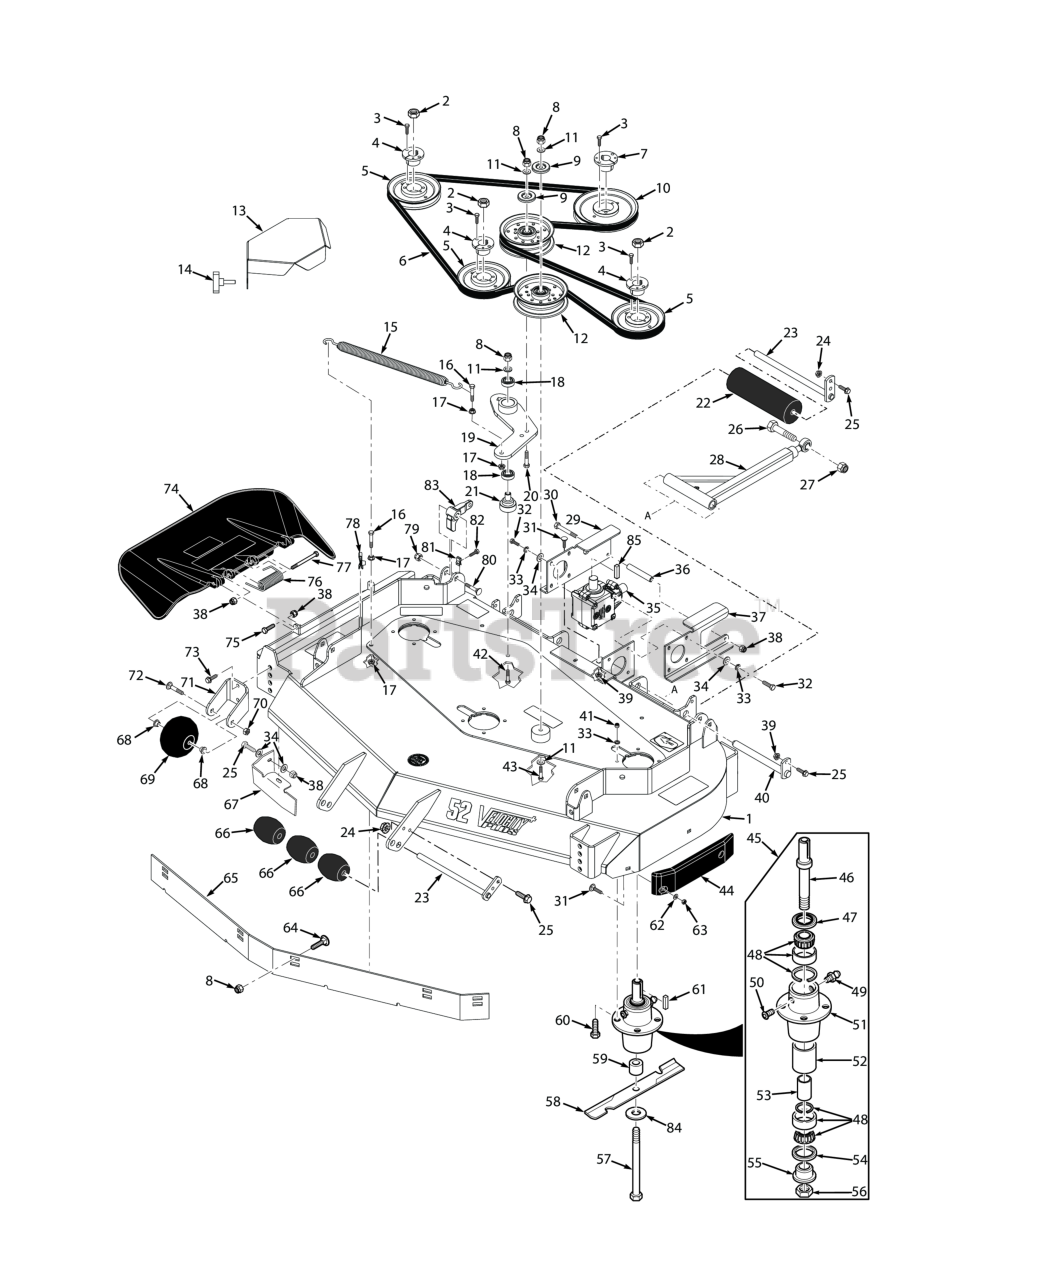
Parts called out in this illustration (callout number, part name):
1	Cutter Deck w/Decals - 52V
2	Hex Locknut, Elastic Stop, 3/8-16
3	Bolt, Hex Head 1/4-20 x 1" Grade 8 Black
4	Hub, Tapered 1-1/8" Bore
5	Pulley, 5.75 O.D. (Gasoline Engines)
6	Belt, Cutter Deck Drive
7	TAPERED HUB, 1.00" BORE
8	HEX NUT, ELASTIC STOP LOCK, 3/8-16
9	Quick Pin, 5/16" Dia.
10	Pulley, 6.95" O.D. - 72"
11	Flatwasher, 3/8 (.391 x .938 x .105 HD) Grade 8
12	Idler Pulley, Belt Clutch
13	Belt Cover LH
14	Knob, w/stud 3/8-16 x 1-1/4"
15	Spring, Cutter Deck
16	Bolt, Hex Head 3/8-16 x 1-1/2" Grade 8 Black
17	NUT, 3/8-16 SERRATED FLANGE HEX HEAD
18	BEARINGS, BALL, NEUTRAL RETURN
19	Idler Arm, Cutter Deck
20	Capscrew, Hex Head 3/8-16 x 2.75"
21	Pivot, Idler - Short
22	Wheel, Anti-ScalpRelief Fitting, Tapered Spindle
23	Shaft Weldment, Guide Roller
24	Nut, Flange Head Elastic Stop 5/16-18
25	Bolt, Heax Head 5/16-18 x 1" (48V / 52V)
26	BOLT, HEX HEAD 5/8-11 X 4-1/2"
27	HEX LOCKNUT, ELASTIC STOP, 5/8-11
28	Push Arm (Includes 64,60,62)
29	Mounting Plate
30	Bolt, 5/16-18 x 4-3/4" Hex Head
31	Bolt, 5/16-18 x .75 RHSN Carriage
32	Bolt, Heax Head 5/16-18 x 1" (48V / 52V)
33	Lockwasher, 5/16 (.317 x .586 x .078) Helical Spring
34	Flatwasher, 5/16-.375 x .875 x .083 (35BV & 37BV-EFI)
35	Gearbox Assembly, Deck Drive
36	Spacer, Gearbox Mount
37	Mounting Plate
38	HEX NUT, ELASTIC STOP LOCK, 5/16-18
39	Nut, Serrated Flange 5/16-18 (Right Front Engine Mounting, Briggs and Kohler Only)
40	Shaft Weldment, Pusharm
41	Lock Nut, 5/16-18 Elastic Stop Grade 8
42	Bolt, Hex Head 3/8-16 x 3" - 52"
43	Capscrew, Hex Head 3/8-16 x 3-3/4"
44	Pad, Deck Wear
45	Cutter Spindle Assembly
46	Spindle Shaft, Tapered Brng
47	SEAL, 2.00 O.D. X 1.50 BORE
48	Tapered Bearing Set (Two Bearings W/Race)
49	GREASE FITTING, STR. 1/4-28 SELF TAP.
50	RELIEF FITTING, TAPERED BEARING SPINDLE
51	Housing, Spindle
52	Spacer, Outside, Cutter Spindle
53	SLEEVE, CUTTER SPINDLE
54	Seal, 2.00" O.D. x 1.625" Bore
55	SPINDLE BUSHING, BOTTOM
56	Nut , Spec ial 1 -1/ 1 6 - 1 8
57	BOLT, HEX HEAD, 5/8-11 X 9-1/2 GR.5
58	Cutter Blade, 18" (52V)
59	Spacer, Spindle Bottom
60	Bolt, Hex Head 5/16-18 x 1-3/4" Grade 8
61	Key, 1/4 x 1/4 x 2.0"
62	Flatwasher, 5/16-.344 x .688 x .065 (48V / 52V)
63	Nut, Center Lock, 5/16-18(32)
64	Carriage Bolt, 3/8-16 x 1.0"
65	Baffle Custom-Cut, 52V (7-Position)
66	Wheel, Anti-Scalp
67	Turbo Baffle - 48V / 52V
68	Bushing, .376" I.D. Oilite
69	Bolt, Carriage 3/8-16 x 4"
70	Bolt, Hex Head 3/8-16 x 1" Ser. Flg.
71	Bracket, Anti-Scalp Wheel
72	Bolt, Hex Head 3/8-16 x 3-1/2"
73	Capscrew, 3/8-16 x 1.0" Serrated Flange Hex Hd
74	Discharge Chute Assembly - 52V
75	Bolt, Hex Head 5/16-18 x 1-1/2" - Front
76	Spring, Discharge Chute
77	Bolt, 5/16-18 x 4-3/4" Hex Head
78	U-Nut, 3/8-16
79	HEX LOCKNUT, ELASTIC STOP, 7/16-14
80	Bolt, Carriage 7/16-14 x 2-1/4"
81	U-Nut, 3/8-16 (short)
82	Bolt, Hex Head 3/8-16 x 2" Special Lock
83	Lever, Deck Level
84	Flatwasher, 5/8-.688 x 1-3/4 x .134 HD
85	Key, 1/4 x 1/4 x 1.25" Pulley Mtg.
